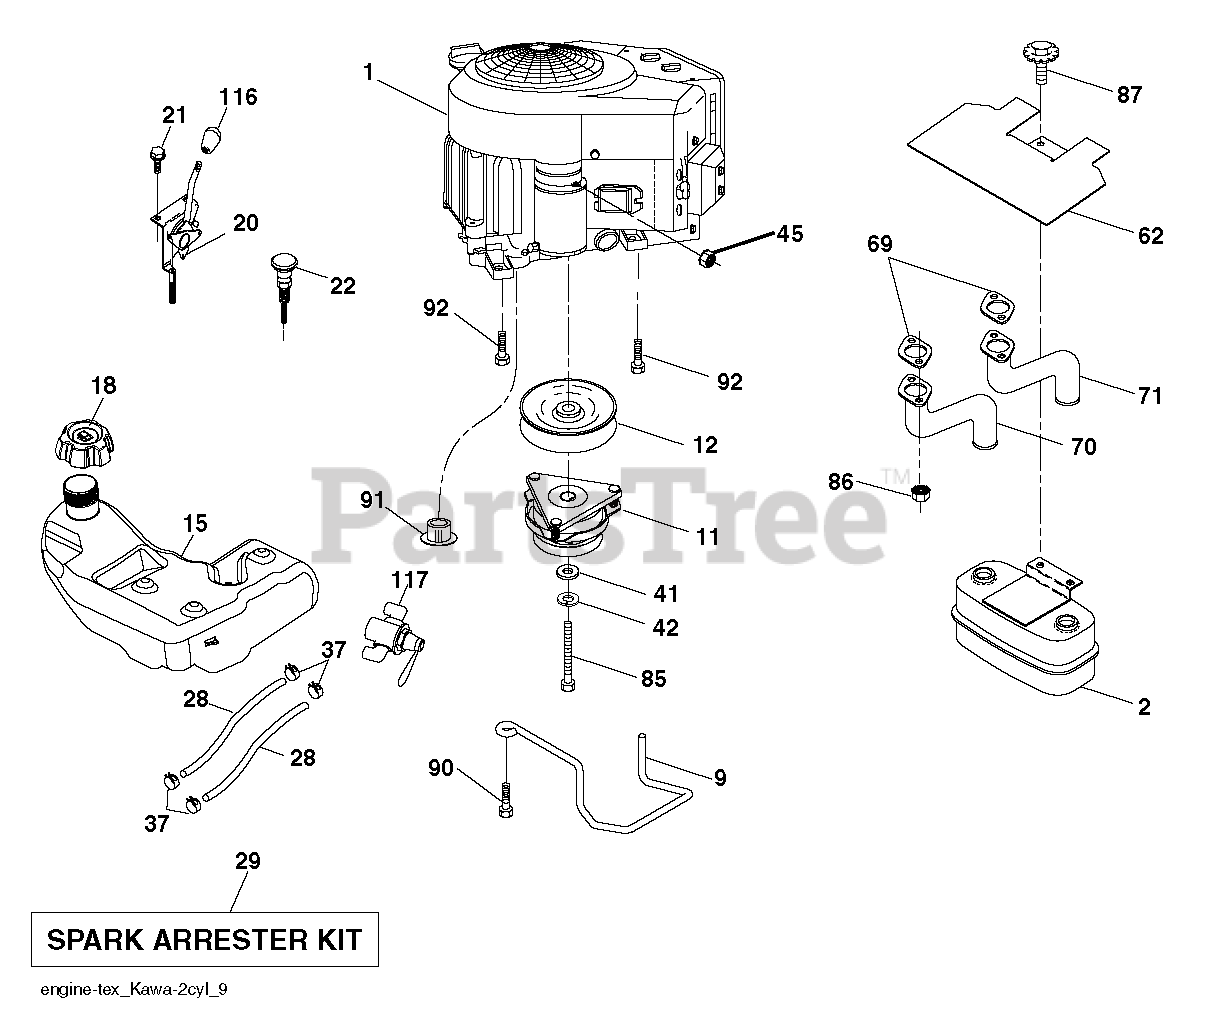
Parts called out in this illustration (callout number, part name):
2	MUFFLER.TWIN.CYL.LOW.TONE
9	KEEPER BELT ENGINE
11	CLUTCH MZ ZTR GT.48/54"1.125"
12	PULLEY ENGINE
15	TANK.ASSY.4.GAL.2.PORT.EPA
18	RP CAP FUEL
20	CONTROL.THROTTLE.PRO.
21	SCREW.#10 X 0.750.BOS
22	CONTROL.CHOKE.ERGO.PUSH-IN.BLA
28	LINE.FUEL.64"REAR.EMIS
29	KIT.SPARK ARRESTOR 794945 B&S
37	HOSE CLAMP
42	LOCKWASHER
45	NUT
62	SHIELD.HEAT.MUFFLER
70	TUBE.EXHAUST.LH.FR961/FR730
71	TUBE.EXHAUST.RH.FR961/FR730
85	BOLT HEX 7/16-20 X 3.75 GR. 5
86	NUT.HEX.FLANGE.TOPLOCK
87	BOLT.5/16-18UNCX1.W/SEMS.BLK
90	SCREW 3/8-16X1
91	BUSHING.1.375OD
92	SCREW 3/8-16X1
116	RP KNOB SOFT TOUCH
117	VALVE FUEL RESERVE
